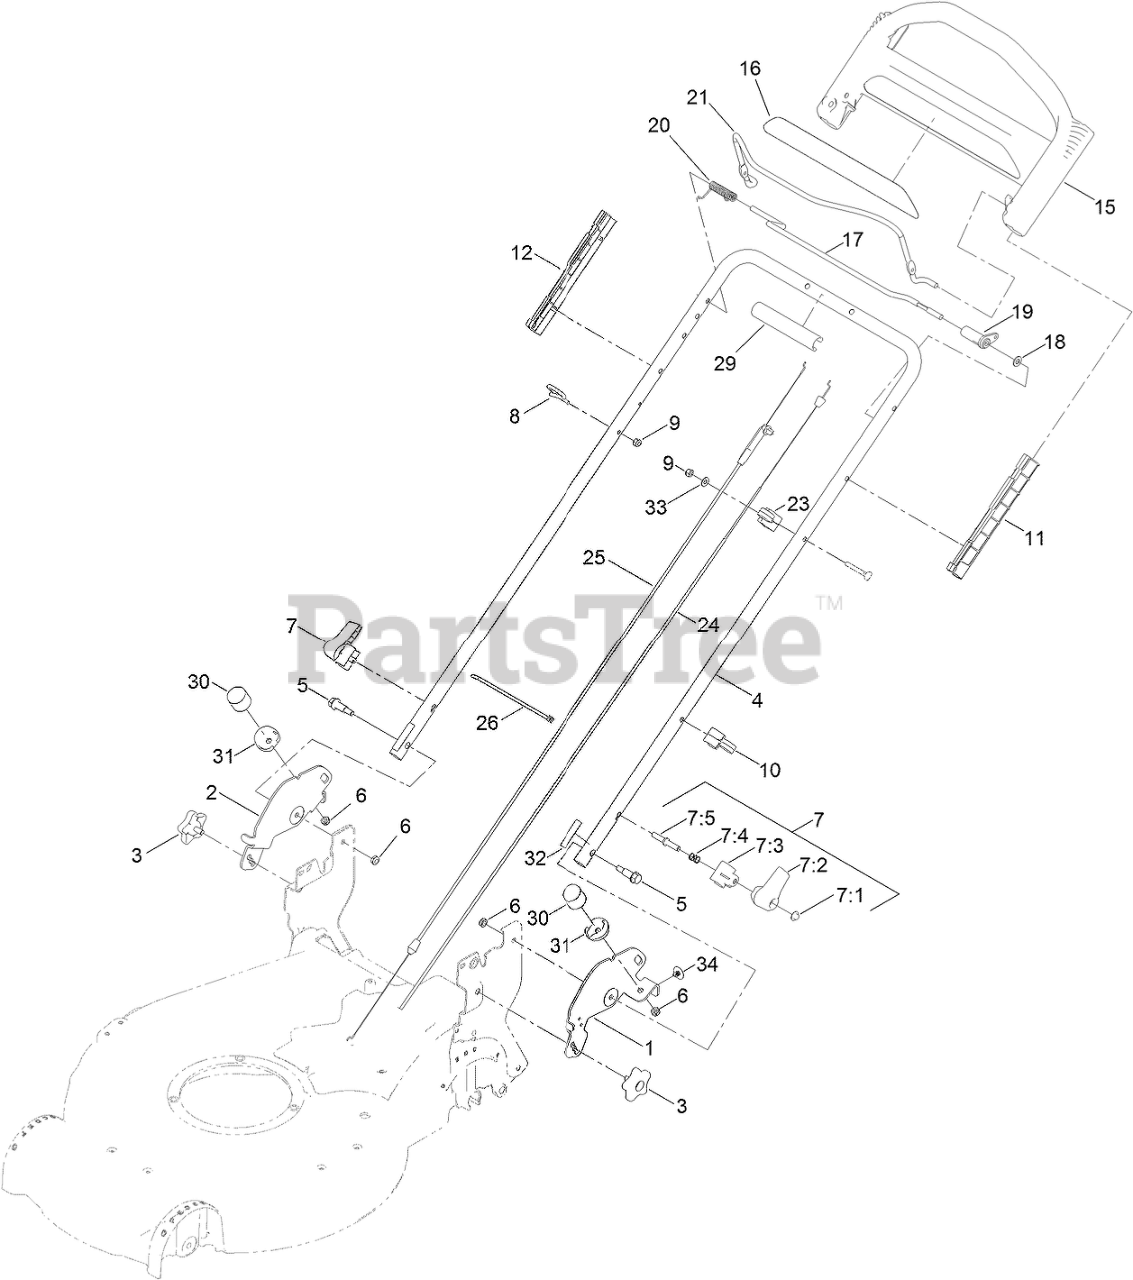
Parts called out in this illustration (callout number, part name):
1	BRACKET-FLOAT, LH
2	BRACKET-FLOAT, RH
3	KNOB-HANDLE
4	HANDLE-UPPER
5	BOLT-SHOULDER
6	NUT-LOCK, NI
7	QUICK RELEASE ASM
7:1	NUT-PUSH
7:2	LEVER-RELEASE
7:3	ANCHOR-SPRING
7:4	SPRING-COMPRESSION
7:5	ROD-RELEASE
8	GUIDE-ROPE
9	NUT-LOCK, NI
10	GUIDE-CABLE
11	GUIDE-LH
12	GUIDE-RH
15	HANDLE-CONTROL
17	BAR-CONTROL, TRACTION
18	WASHER-PLAIN
19	LEVER-TRACTION
20	SPRING-TORSION
21	BAIL-BRAKE
23	ANCHOR-CABLE
24	CABLE-TRACTION
25	CABLE-BRAKE
26	TIE-CABLE
29	HANDLE-COVER
30	BUMPER-RUBBER
31	COVER-BUMPER
32	DECAL-FLEX
33	WASHER-FLAT
34	CLIP-TREE
